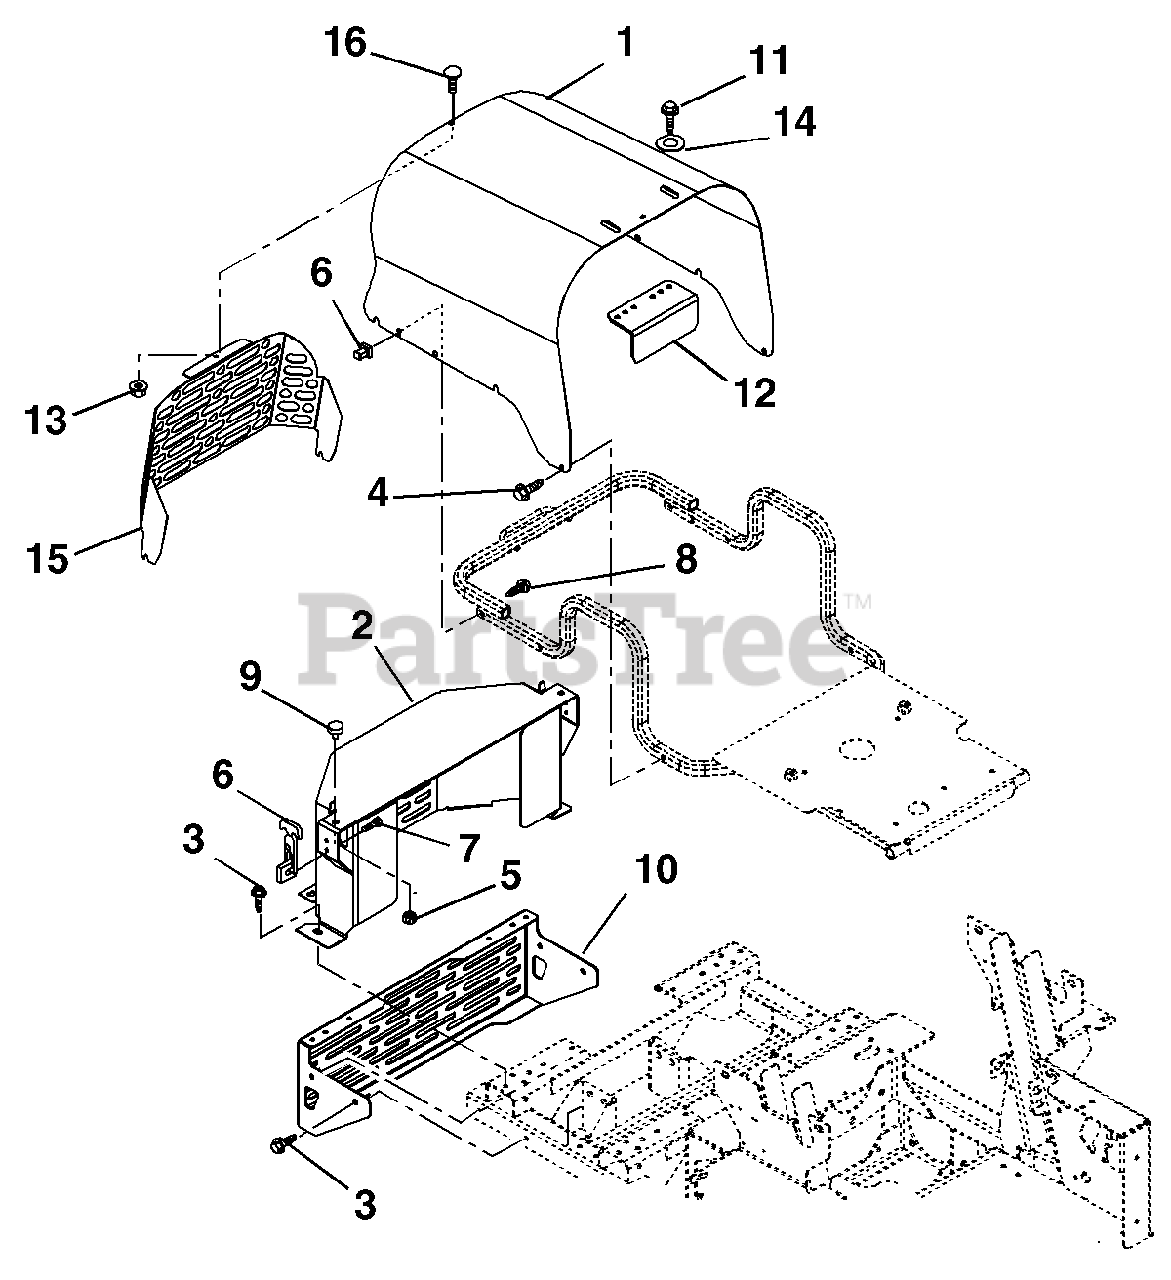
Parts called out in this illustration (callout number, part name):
2	Weldment, Belt Guard (076, 319)
2	Diesel Belt Guard (075, 318)
2	Weldment, Belt Guard (073, 074)
3	Screw, Tapping .38-16 x .75 Hex Washer Head
4	Screw, Tapping .38-16 x .50 Hex Washer Head
5	Nut, Spin Lock, Flange .312-18
6	Latch, Rubber
7	Screw, Machine 10-24 x .50 Hex Washer Head
8	Screw, Machine 10-24 x 1.50 Hex Washer Head
9	Button, Bumper
10	Bumper, Rear
11	Screw, Tapping .25-20 x .50 Hex Washer Head
12	Guard, Radiator Cap
13	Nut, Locking Top Flange .25-20
14	Washer, Flat Steel .281 x .62 x .065
15	Guard, Hood
16	Bolt, Round Head Square Neck .25-20 x .50 Grade 5
